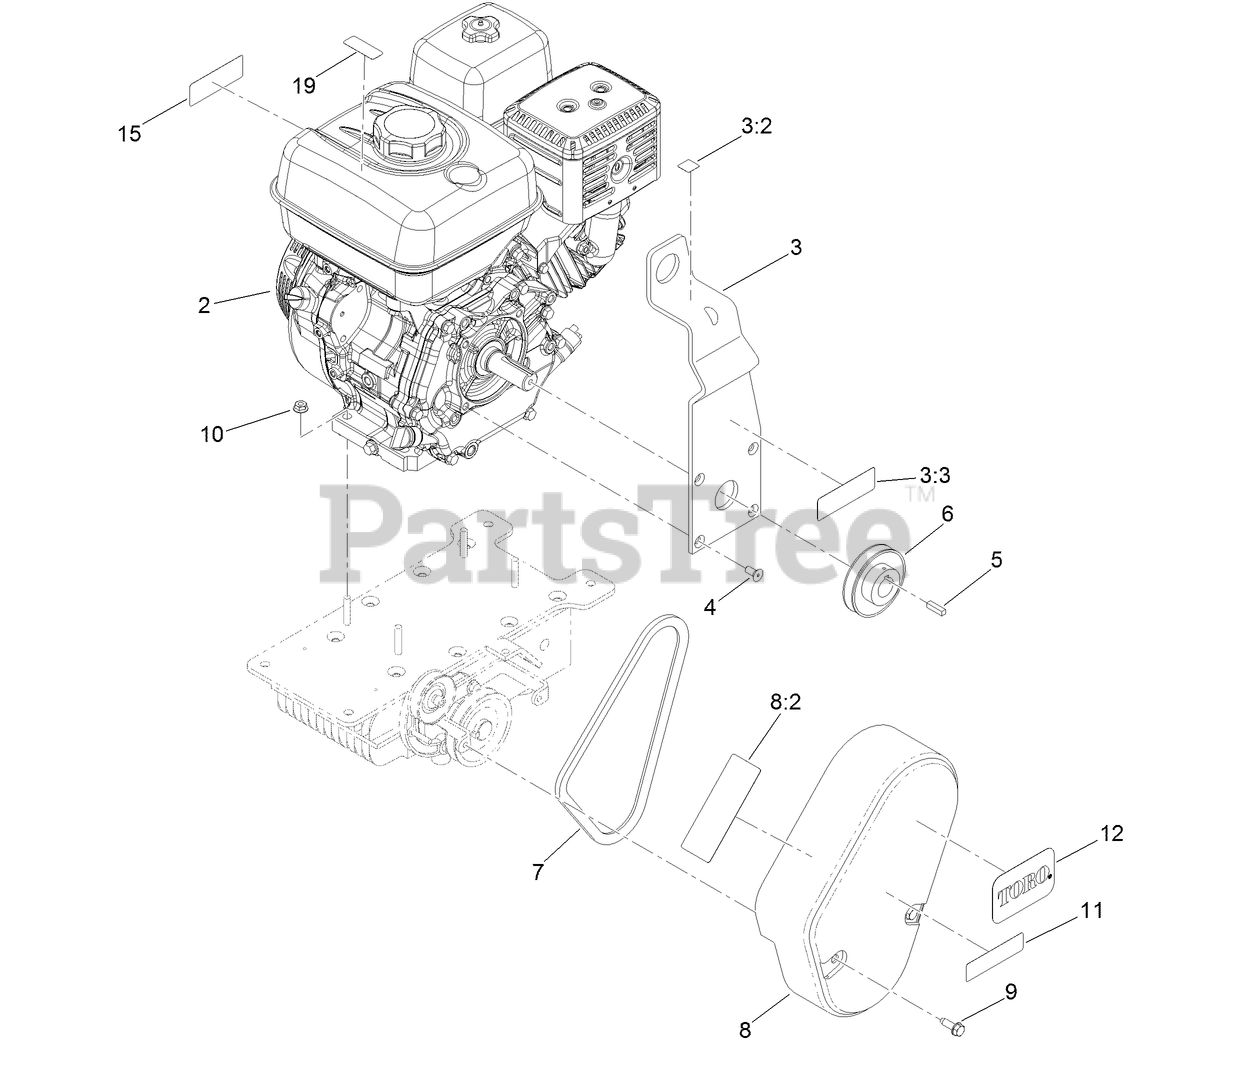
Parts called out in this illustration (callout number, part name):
3	PLATE-EYE, LIFT
3:2	DECAL-POINT, LIFT
3:3	DECAL-WARNING
4	SCREW
5	KEY-SQUARE
6	SHEAVE
7	BELT-V
8	BELT GUARD ASM
8:2	DECAL-WARNING
9	SCREW-THD ROLL, HWH
10	NUT-FLANGE
15	DECAL-ARRESTOR, SPARK
19	DECAL-WARNING, ETHANOL
